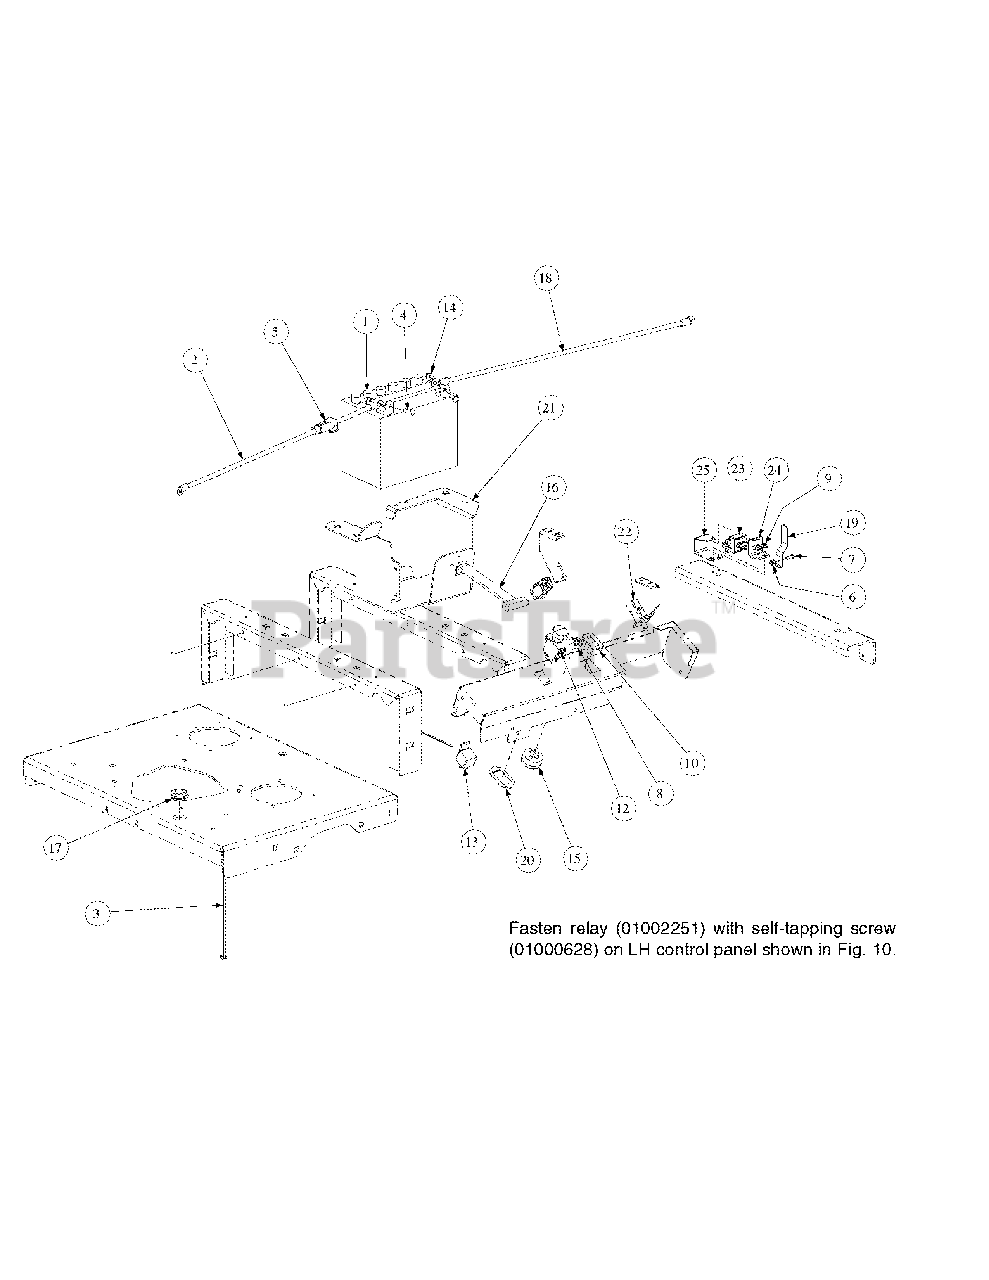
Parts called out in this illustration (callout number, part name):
1	Battery, 12V 225CCA 30 Min
2	Cable, Battery, Red, 36"
3	Tie, Cable, 3/16 x .05 x 7.4"
4	Screw, Hex, Cap, 1/4-20 x .75
5	Boot, 1" OD Rubber Battery-PST, Red
6	Lock Nut, Nylon Insert
7	Screw, Phillips Head, Machine, 10-32 x 5/8
8	Nut, W/Cap, 5/8-32 Ignition
9	Screw, TT, 1/4-20, 0.5, Hex Index Washer
10	Meter, Hour
11	Hourmeter, Harness
12	Switch, Electric, PTO
13	Relay, 12V 40A
14	Lock Nut, 1/4-20
15	Switch, Ignition, 6 Pin
16	Strap, Battery
17	Grommet, .75 ID
18	Cable, Battery Red, 28"
19	Spring Retainer
20	Bracket, PTO Switch Retainer
21	Mount Bracket, Battery
22	Switch, Safety N.O./N.C.
23	Switch, Plunger
24	Bracket, Plunger Switch
25	Clamp, Plunger Switch
26	Harness Assembly
